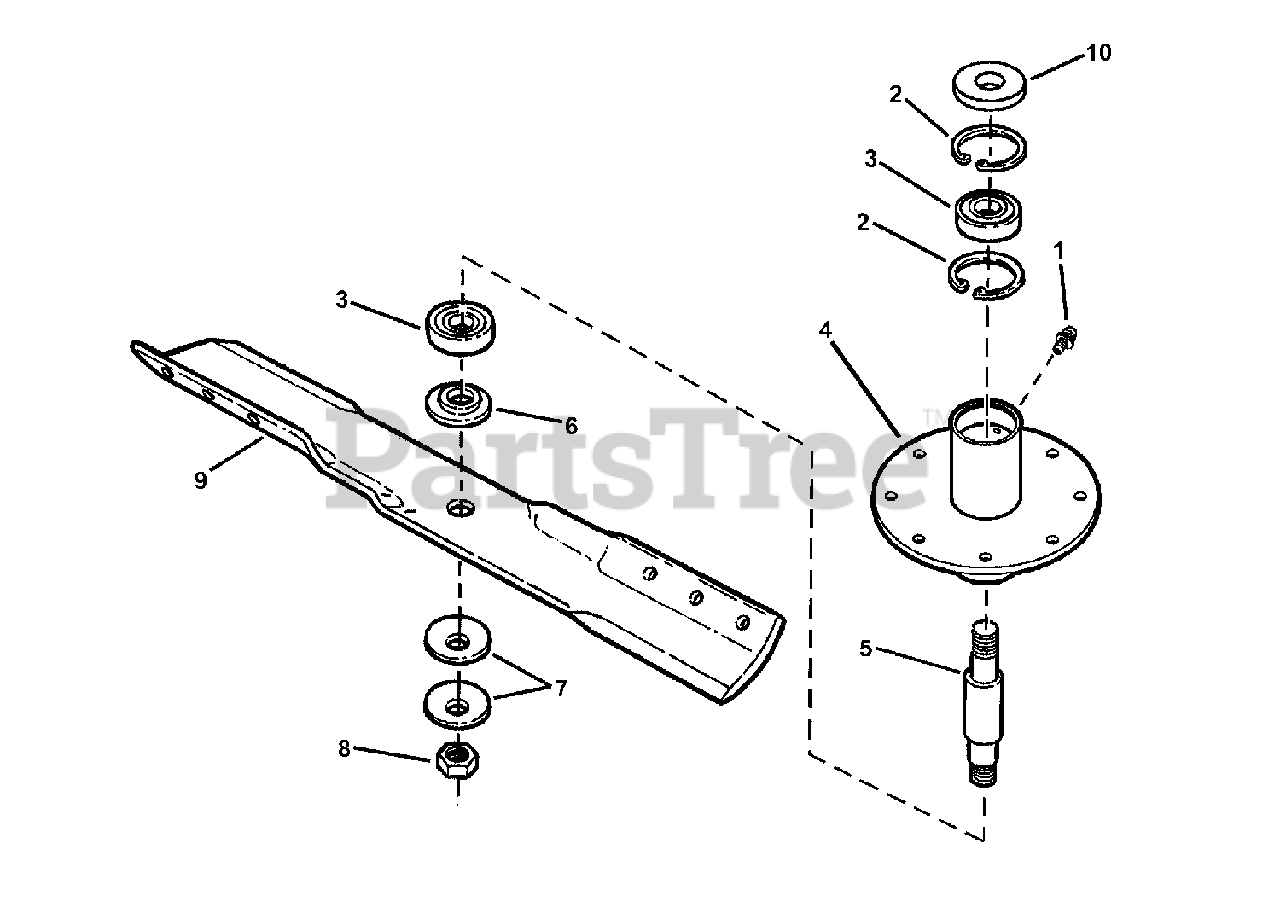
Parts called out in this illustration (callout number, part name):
1	FITTING, Lube, Press-In (for .187 dia. Hole)
2	RING, 1-3/4" External Retaining Ring
3	BALL BEARING, 3/4" I.D.
4	WELDMENT, 48" Spindle Housing
5	SHAFT, Blade Spindle (7.155" long)
6	WASHER, Spindle Blade
7	WASHER, Belleville 9/16 x 1-3/4"
8	NUT, 9/16-18 Hex, GR B
9	BLADE, 19.64 (38 Deck)
10	SPACER, Pulley
